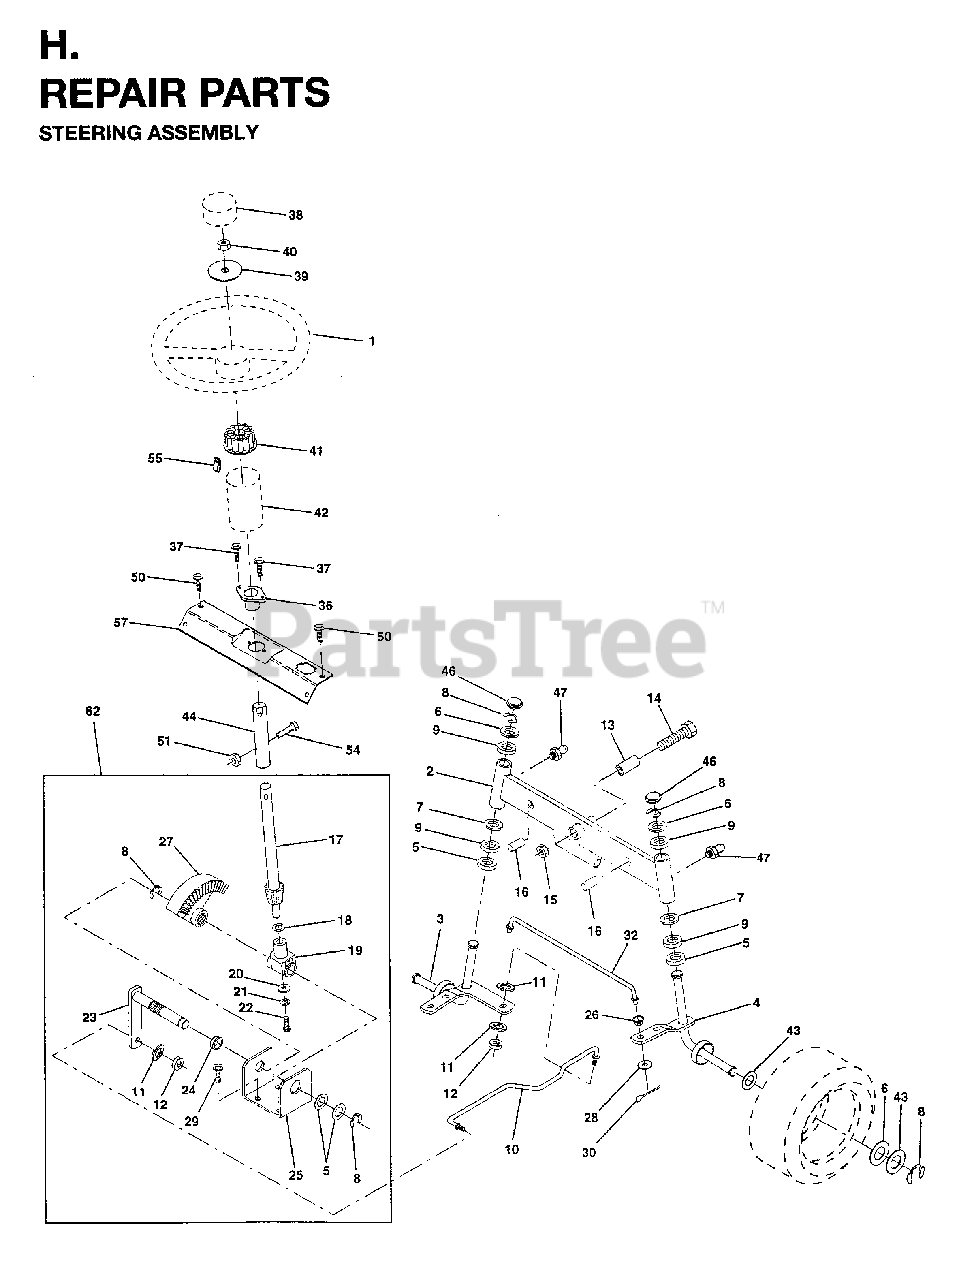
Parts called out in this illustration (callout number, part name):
2	AXLE ASSY
3	SPINDLE LH
4	SPINDLE RH
5	WASHER THRUST
8	RING CLIP
9	BEARING.STEERING.COLUMN
10	DRAG LINK
11	WASHER, LOCK 3/8
12	NUT
13	BEARING
14	BOLT.HEX.5/8-11
15	LOCKNUT
17	SHAFT STEERING
18	THRUST WASHER
19	SHAFT,SUPPORT
20	WASHER
21	LOCKWASHER
22	SCREW
23	SHAFT PITMAN
24	NYLINER T
25	BRKT,STEERING
26	BUSHING.DRAGLINK
27	GEAR.SECTOR
28	WASHER
30	COTTER PIN
32	TIE ROD
36	BUSHING-STRG LT
38	RP INSERT
39	WASHER T
40	NUT
41	ADAPTER-WHEEL LT
42	BOOT STEERING SHAFT
44	STEERING SHAFT
46	CAP.SPINDLE
47	ZERK M
51	NUT.71038.31-18.HEX.NYLOCK
54	BOLT.5/16-18X1-1/4 FULL.THREAD
57	SUPPORT STEERING SHAFT
62	KIT, STEERING ASSEMBLY
